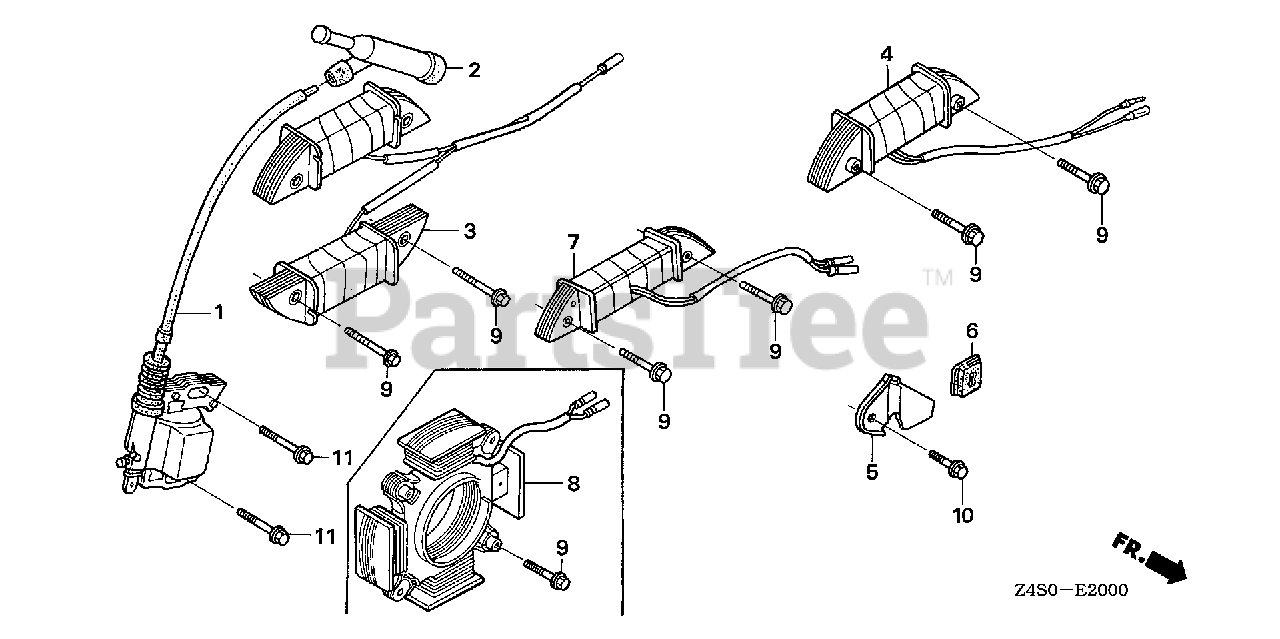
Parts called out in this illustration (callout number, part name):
1	COIL ASSY., IGNITION Use up to Engine SN 1530314.
2	CAP ASSY., NOISE SUPPRESSOR (Honda Code 3526837). (NICHIWA Y-EZ RTFM256)
11	BOLT, FLANGE (6X25) Use up to Engine SN 2056819.
